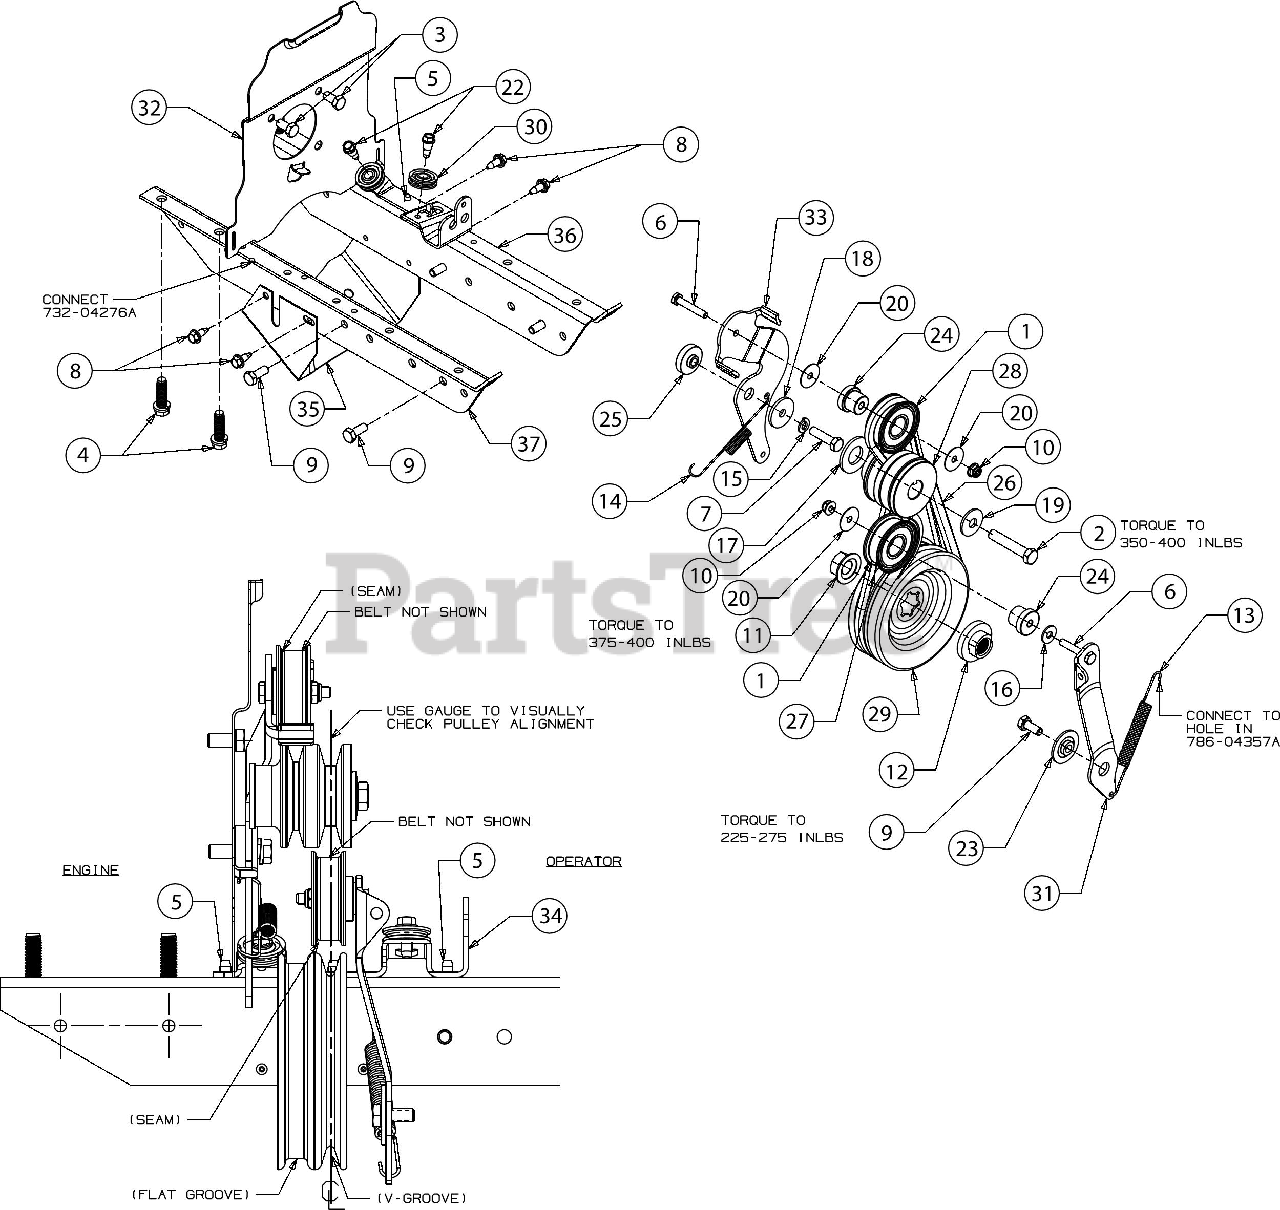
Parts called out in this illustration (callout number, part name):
1	IDLER PULLEY ASSEMBLY
1	BEARING SLEEVE
1	BALL BEARING
2	HEX SCREW 3/8-24 X2.00
3	HEX SCREW 5/16-24 x .62
4	SCREW 3/8-16 x 1.250
5	SCREW 1/4-20 X.500
6	SCREW 1/4-20 x 1.50 GR.5
7	SCREW 5/16-24 x 1.25 GR5
8	SCREW 1/4-14 x .625
9	SCREW 5/16-18 x .750
10	FLANGE LOCK NUT
11	FLANGE NUT W/HUB
12	PULLEY HUB
13	RETURN SPRING
14	EXTENSION SPRING
15	LOCK WASHER 5/16
16	FLAT WASHER .28 ID x .74 OD x .063
17	FLAT WASHER
18	WASHER-5/16 x 1.25X 1.27
19	BELL WASHER
20	FLAT WASHER
22	SHOULDER SCREW
23	PIVOT IDLER SPACER
24	SHOULDER SPACER
25	PIVOT IDLER SPACER
26	V-BELT FWD DRIVE 4L x 25.375
27	V-BELT REV DRIVE 3L x 29.125
28	ENGINE PULLEY
29	TRANSMISSION PULLEY
30	CABLE GUIDE ROLLER
31	FORWARD IDLER BRACKET
32	REVERSE IDLER BRACKET
33	REVERSE IDLER BRACKET
35	PULLEY SHIELD
36	RH FRAME MOUNT
37	LH FRAME MOUNT
